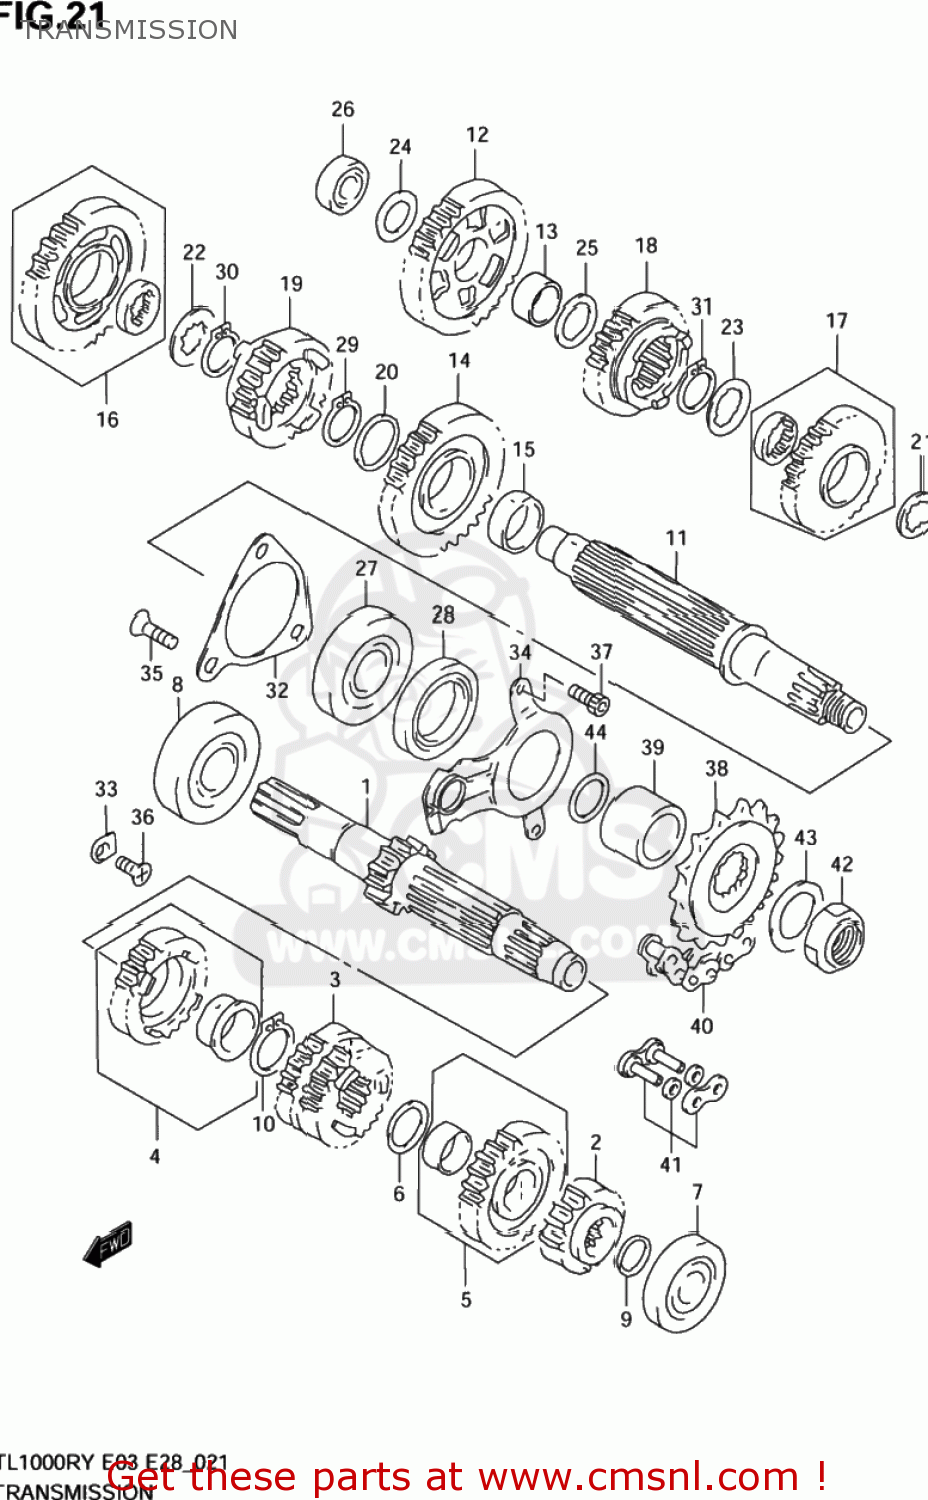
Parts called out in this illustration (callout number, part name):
1	SHAFT,COUNTER(NT:12)
2	GEAR,2ND DRIVE(NT:15)
3	GEAR,3RD & 4TH DRIVE(NT:18/27)
4	GEAR SET,FIFTH DRIVE (NT:
5	GEAR SET,SIXTH DRIVE (NT:
6	SHIM(22X30X1)
7	BEARING(20X47X14)
8	BEARING(25X62X17)
9	O RING(D:1.9,ID:16.6)
10	CIRCLIP
11	SHAFT,DRIVE
12	GEAR,1ST DRIVEN(NT:32)
13	BUSH
14	GEAR,2ND DRIVEN(NT:29)
15	BUSH,2ND DRIVEN GEAR
16	GEAR SET,THIRD DRIVEN (NT
17	GEAR SET,FOURTH DRIVEN (NT
18	GEAR,5TH DRIVEN(NT:25)
19	GEAR,SIXTH DRIVEN (NT:24)
20	WASHER(27X36X1)
21	WASHER,LOCK
22	WASHER,3RD & 4TH DRIVEN
23	WASHER,3RD & 4TH DRIVEN
24	SHIM(20X34X1)
25	SHIM(22X34X1)
26	BEARING(20X52X15)
27	BEARING(28X68X20)
28	SEAL,OIL(38X52X8)
29	CIRCLIP
30	CIRCLIP
31	CIRCLIP
32	RETAINER,DRIVE SHAFT BEARING
33	RETAINER
34	RETAINER,DRIVESHAFT O
35	SCREW(6X12)
36	SCREW
37	BOLT,STRANGER
38	SPROCKET,ENGINE(NT:17)
39	SPACER,ENGINE SPROCKET
40	CHAIN,DRIVE
41	JOINT SET
42	NUT
43	SHIM(25X40X1.5)
44	O RING(D:2.4,ID:23.7)
